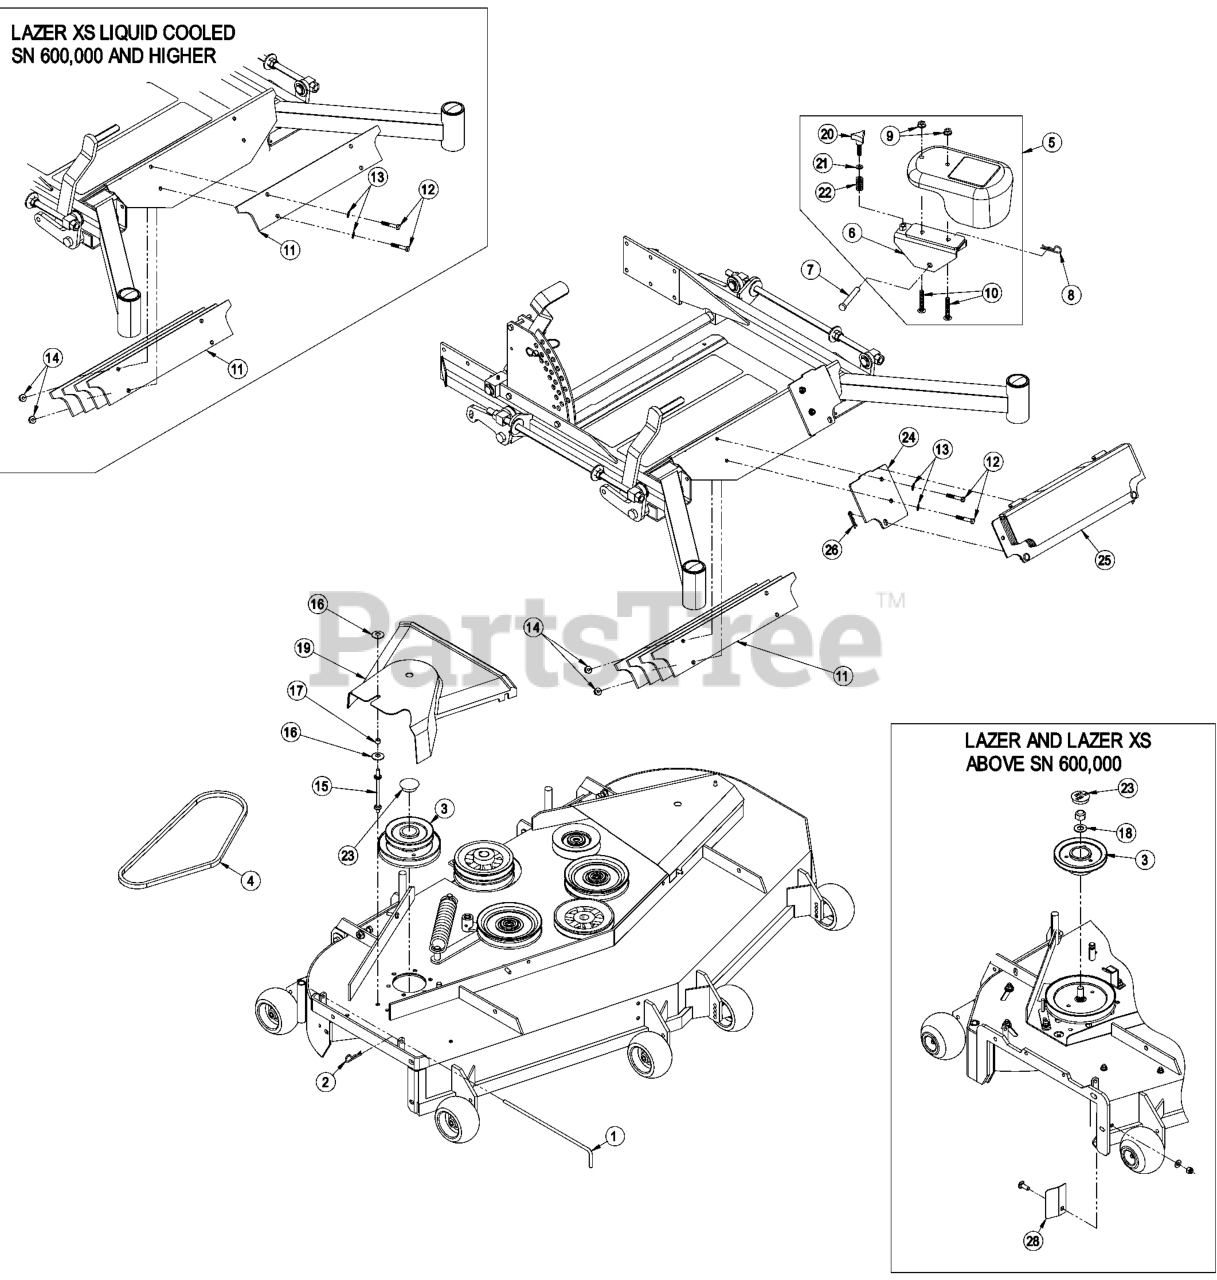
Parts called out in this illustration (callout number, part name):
1	PIN,CHUTE PIVOT
2	PIN-COTTER
3	JACKSHAFT, LZUV60
4	BELT, BLOWER 52"DECK
5	ASM, WEIGHT 1.5" 70 POUND
6	WLD, BRACKET 2.0 ARM
7	PIN-CLEVIS
8	PIN-COTTER
9	NUT-HHF, WHIZ
10	BOLT-SQH
11	PLATE, WEIGHT
12	SCREW-HH
13	WASHER-PLAIN
15	STUD,BELT SHIELD 4 INCH
16	WASHER-SPRING
18	WASHER-FLAT
19	COVER, BELT LZ52
21	WASHER-FLAT
23	PLUG, BLACK NYLON 1.75
24	PLATE, WEIGHT MOUNTING
25	ASM, WEIGHT PLATE WITH DE
26	PIN-HAIR
28	DEFLECTOR,LZ UV
